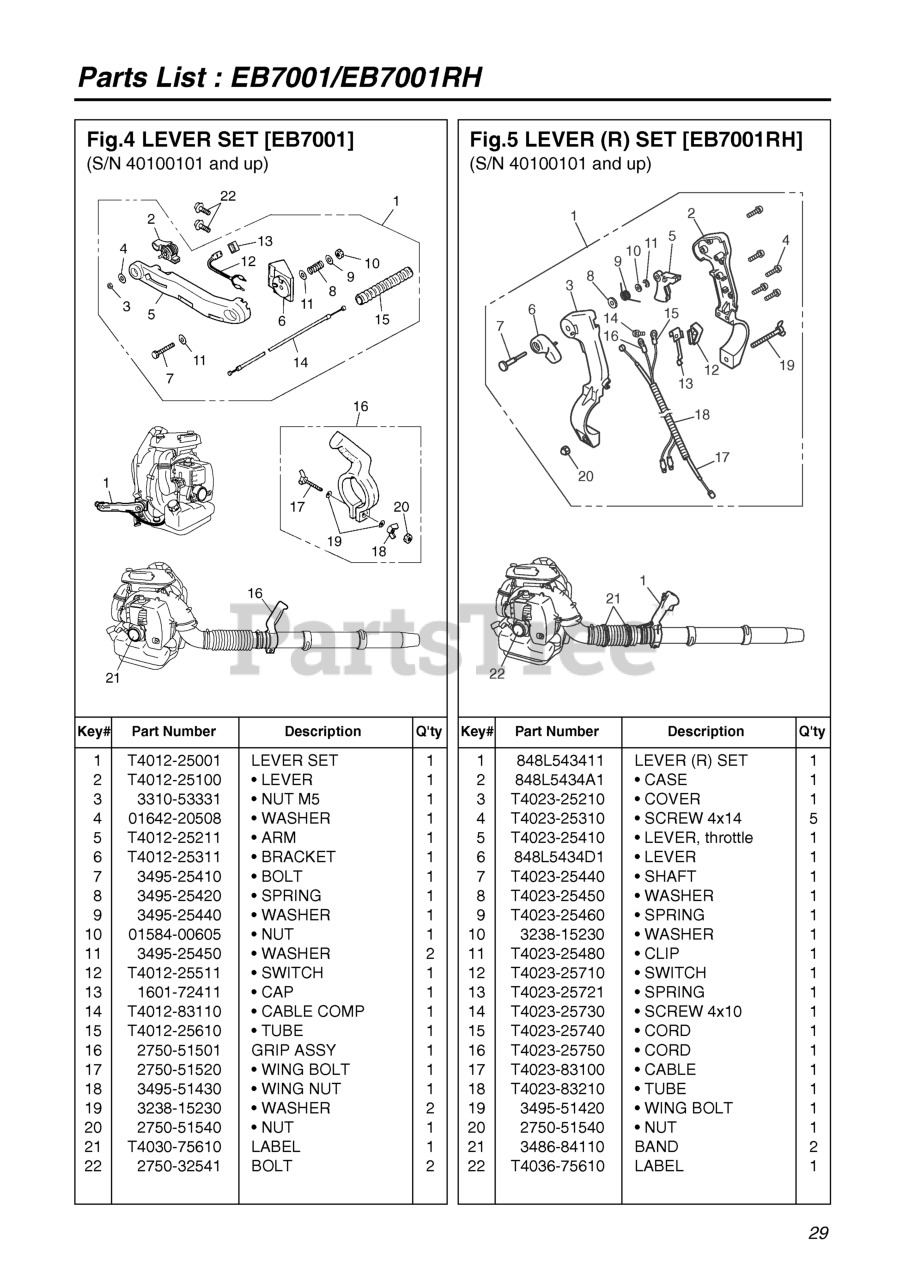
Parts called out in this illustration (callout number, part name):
A2	LEVER
A3	NUT (B)
A4	WASHER, M5x.8(RPLS 01624-20508
A5	ARM (RPLS T4012-25210)
A6	BRACKET (RPLS -25310)
A7	BOLT
A8	SPRING
A9	WASHER
A10	NUT, M6 X 5
A11	WASHER, FLAT
A12	SWITCH (RPLS T4012-25510)
A13	CAP SWITCH
A14	CABLE COMPLETE
A16	GRIP ASSEMBLY (RPLS -51500)
A17	WING BOLT
A18	NUT, WING
A19	WASHER
A20	NUT
A21	RECOIL LABEL, EB7001
A22	BOLT, M5 X 16 (RPLS -32540)
